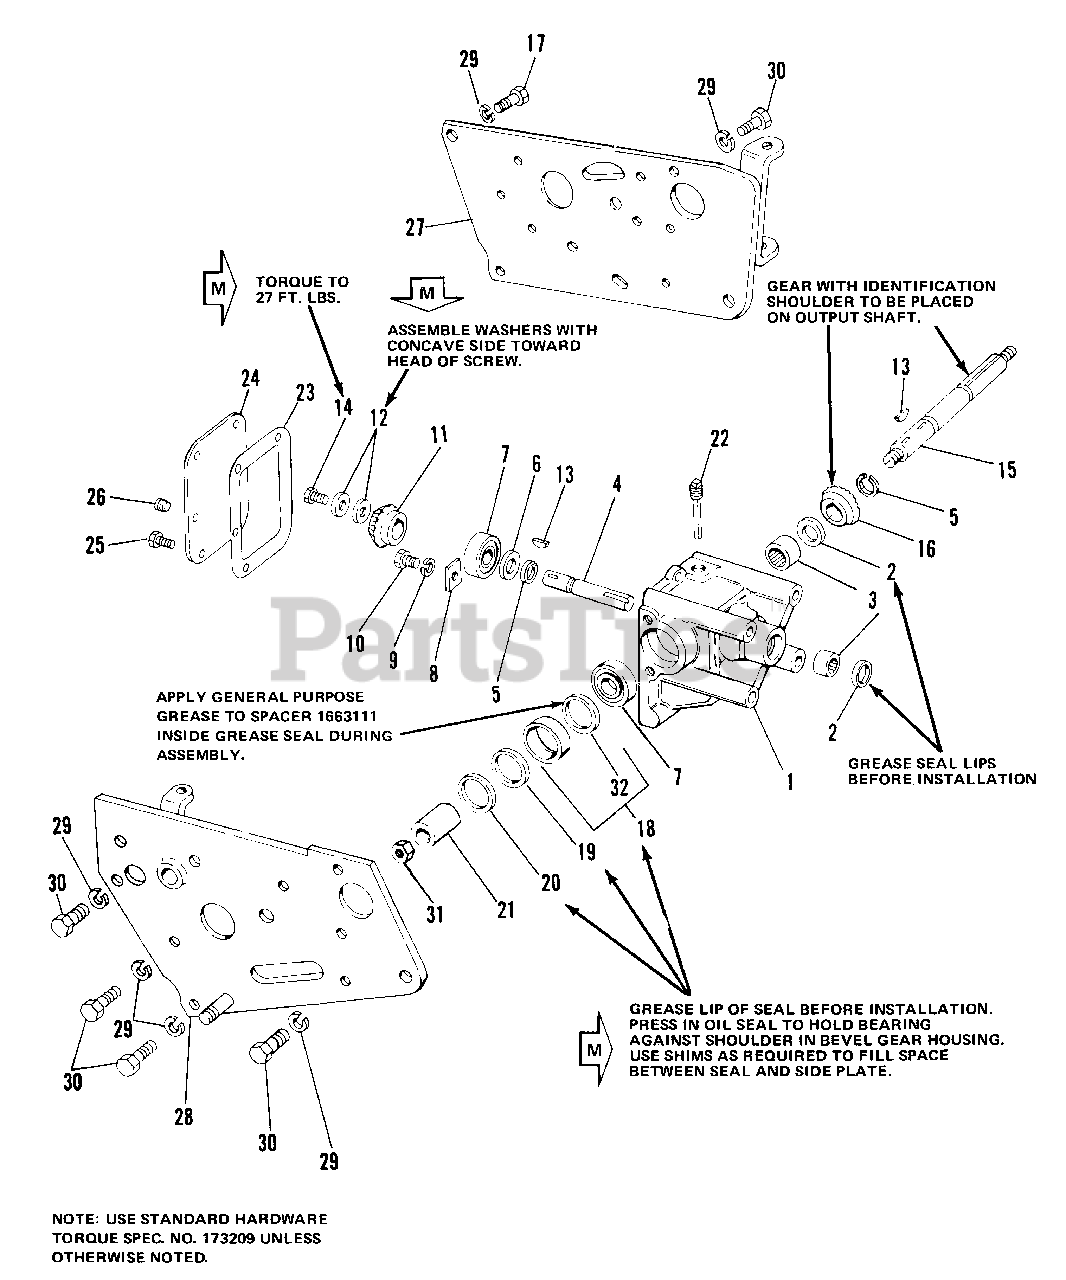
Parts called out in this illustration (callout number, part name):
1	HOUSING, Bevel Gear
3	BEARING, Needle
4	SHAFT, Driver
5	RING, Retaining
7	BEARING, Ball
8	PLATE, Bearing Clamp
9	LOCKWASHER, 5/16
10	CAPSCREW, Hex Hd., 5/16-18 x 5/8
11	GEAR, Bevel Driver
13	KEY, Woodruff, No. 9
14	CAPSCREW, Hex Hd., 5/16-18 x 3/4
15	SHAFT, Driven
16	GEAR, Bevel Driven
17	CAPSCREW, Hex Hd., 7/16-14 x 1-1/4
25	CAPSCREW, Hex, 1/4-20 x 5/8
27	PLATE ASSY, Side, L.H.
28	PLATE ASSY, Side, R.H.
29	LOCKWASHER, 7/16
30	CAPSCREW, Hex Hd., 7/16-14 x 1
31	LOCKNUT, Hex,Jam, 3/4-16
32	SPACER, Oil Seal
